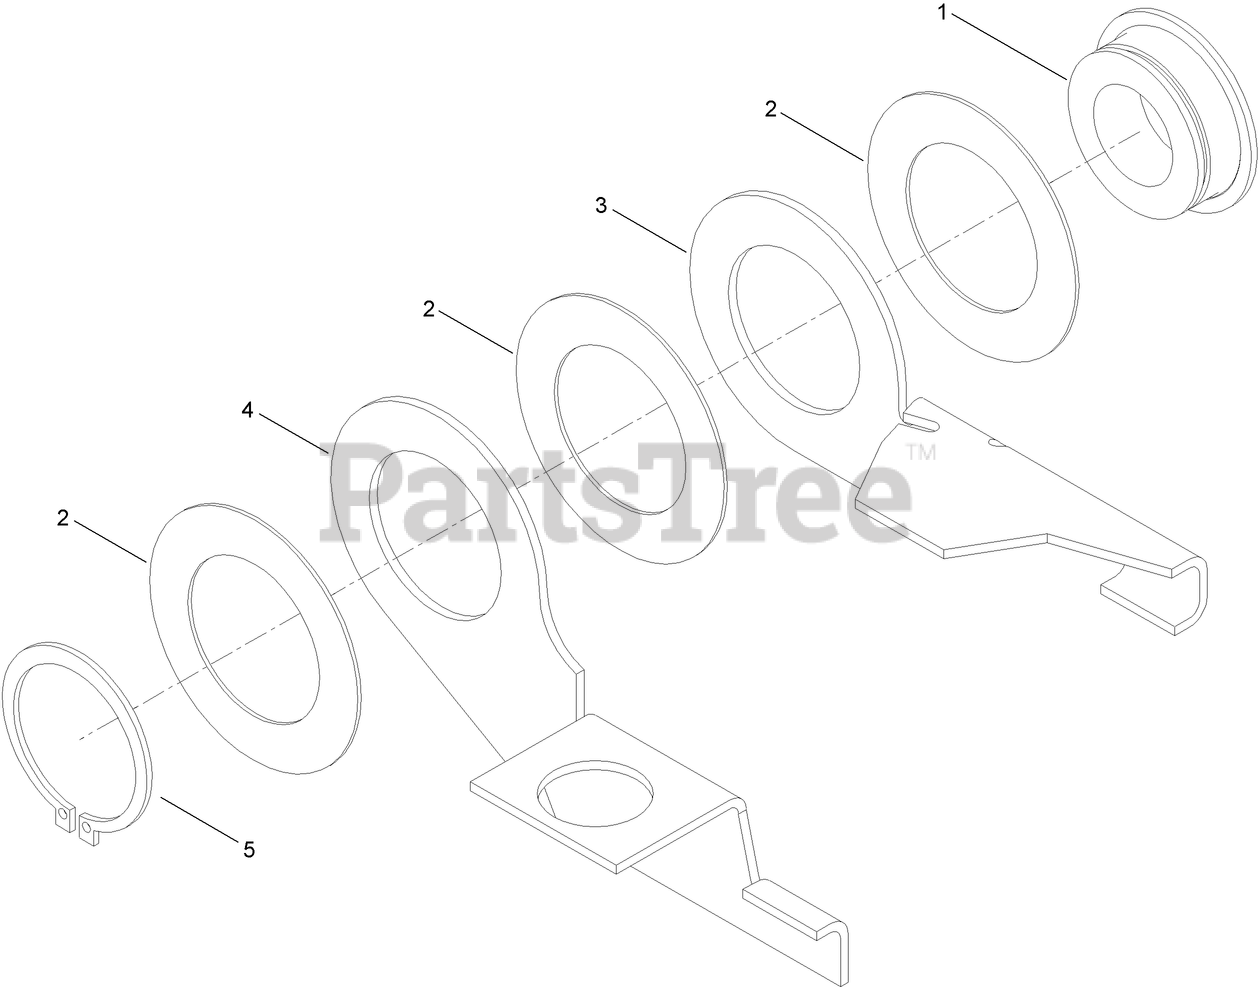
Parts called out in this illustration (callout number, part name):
3	PLATE-MOUNTING, SWITCH
4	PLATE-MOUNTING, SWITCH
5	RING-RETAINING
